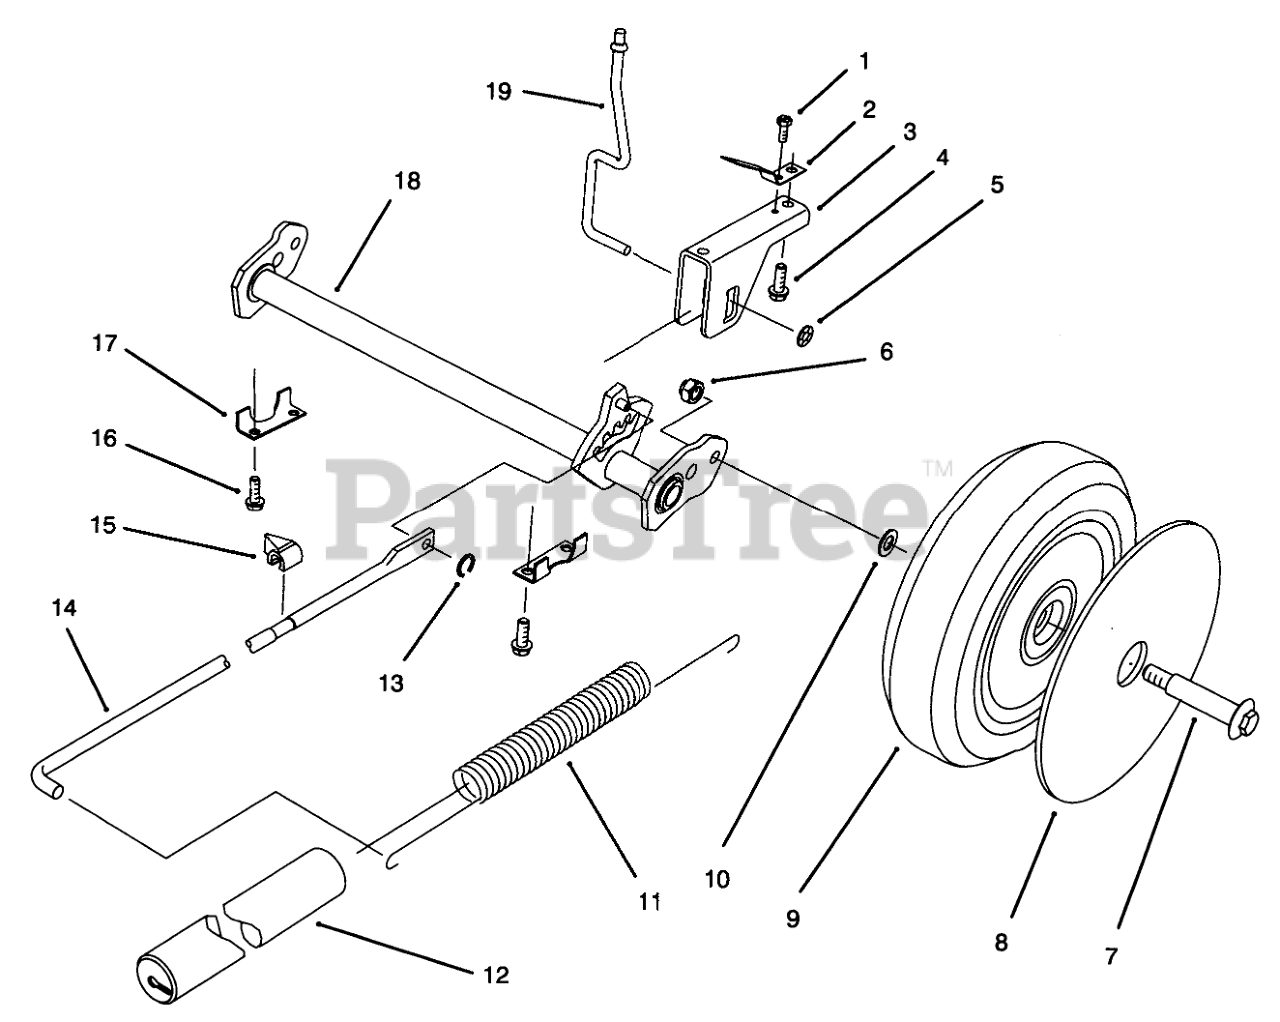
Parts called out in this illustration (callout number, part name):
1	SCREW 8 - 32 X 250
2	SPRING - TRIGGER RET
3	SADDLE - HOC
4	SCREW
5	PUSHNUT
6	NUT-HEX
7	BOLT-WHEEL
8	COVER-WHEEL
9	Wheel-ASM
10	WASHER
11	SPRING-COUNTERBALANCE
12	COVER-SPRING
13	GRIP RING
14	LINK ROD
15	INDICATOR-HEIGHT OF CUT
16	SCREW-HWH
17	REAR SECURING PLATE
18	PIVOT ARM REAR WA
19	TRIGGER ROD
